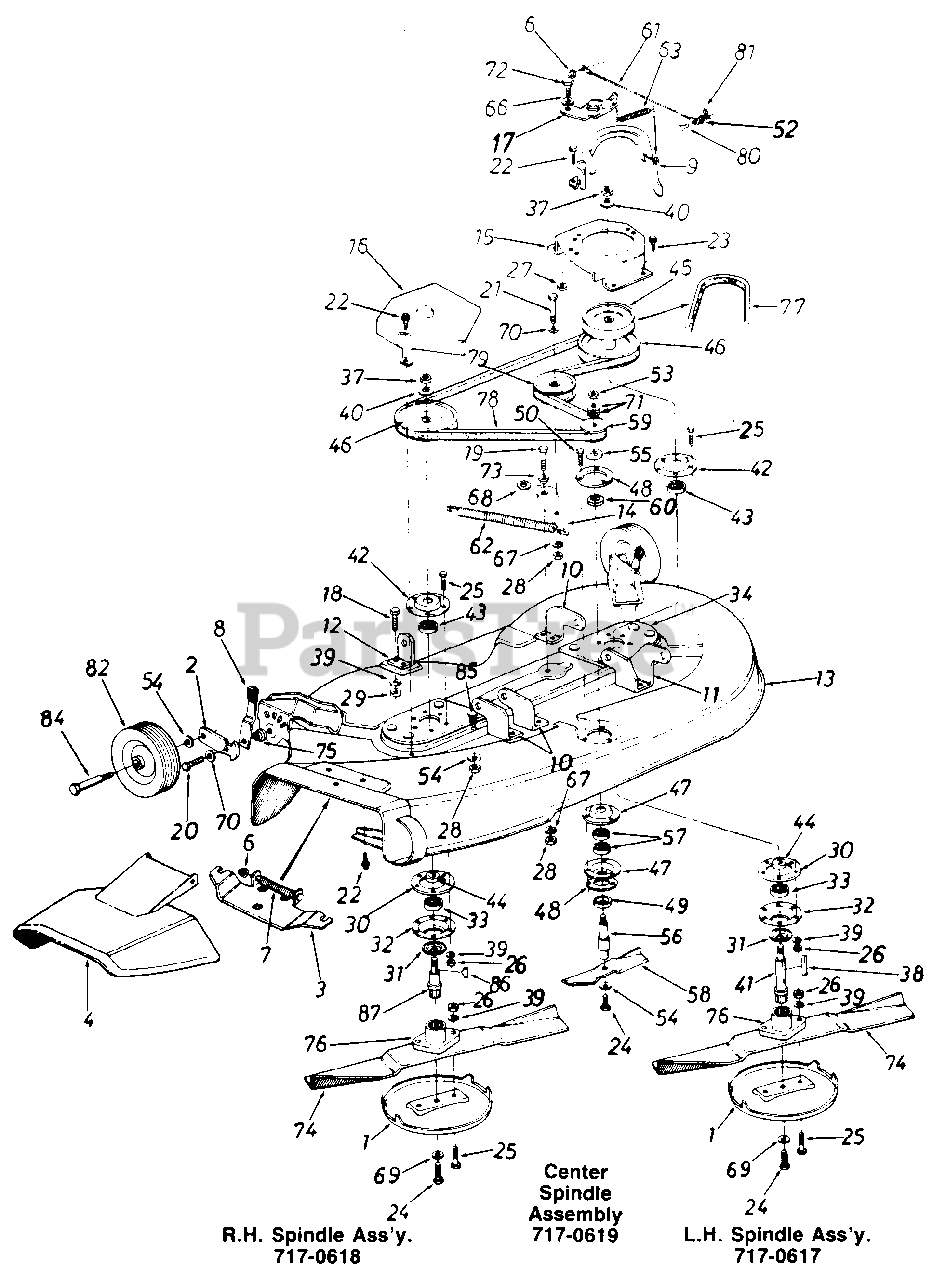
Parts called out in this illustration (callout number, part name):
1	Anti-Scalp Plate
2	Bar-Wheel Pivot
3	Adapter Plate
4	Chute Cover Ass'y.
6	Cap Speed Nut 1/4" Rod
7	Torsion Spring
8	Spring Lever Ass'y.
9	Belt Guard
12	Deck Hanger Bracket
13	44" Deck Ass'y.
14	Idler Bracket
15	Pulley Cover L.H.
18	Hex Bolt 5/16-18 x .75" Lg.
19	Hex Bolt 3/8-24 x 1.00" Lg.
20	Hex Bolt 3/8-24 x 1.25" Lg.
21	Hex Bolt 3/8-24 x 1.50" Lg.
22	Hex Wash. S-Tapp Scr. 1/4-20 x .50
23	Hex Wash. Hd. Tapp Scr. 5/16-18 x .75" Lg.
24	Hex Cent. L-Bolt 3/8-24 x .88" Lg.
25	Hex Bolt Special 5/16-24 x 1.0" Lg.
26	Hex Nut 5/16-24 Thd.
27	Hex Cent. L-Nut 5/16-18 Thd.
28	Hex Nut 3/8-24 Thd.
29	Hex Nut 5/16-18 Thd.
30	Reinforcement Plate
31	Bearing Shield
32	Open Brg. Housing 1.85 I.D.
33	Ball Brg. .787" I.D. x 1.85" O.D. x .551
34	Spindle Mounting Plate Ass'y.
37	Hex Jam Nut 5/8-18 Thd.
38	Sq. Key 3/16" x 2.25" Lg.
39	L-Wash. 5/16" I.D.
40	Bell-Wash. .630" I.D. x 1.25" O.D.
41	44" Deck Blade Spindle
42	Bearing Housing 1.85" I.D.
43	Ball Brg. .787" I.D. x 1.85" O.D. x .551
44	Spacer 1.0" O.D. x .790" I.D.
45	5/8 "V"-Pulley .79" I.D. x 5.75" O.D.
46	"V"-Pulley .79" I.D. x 6.50" O.D.
47	Bearing Housing 1-3/8" I.D.
48	Reinforcement Plate
49	Bearing Shield
50	Hex Wash. Hd. B-Tap Scr. 1/4 x.75" Lg.
52	Fl-Wash. .20" I.D. x .62" O.D.
53	Hex Jam Nut 1/2-20 Thd.
54	Bell-Wash. .400" I.D. x .88" O.D.
55	Fl-Wash. .635" I.D. x 1.04" O.D.
56	6.5" Blade Spindle
57	Ball Brg. .62" I.D. x 1.38" O.D. x .44
58	6.5" Blade
59	1/2" "V"-Puley Half .625" I.D. x 2.25" O.D.
60	Fl-Wash. 5/8" I.D. x 15/16" O.D.
61	Brake Cable 11.75" Lg.
62	Extension Spring .73" O.D. X 4.31 n Lg.
63	Ext. Spring .50" X 2.51" Lg.
66	Spring Wash. .445" I.D. x 75" O.D.
67	L-Wash. 3/8" I.D.
68	Spring Wash. .625" I.D. x .885" O.D.
69	L-Wash. 3/8" I.D.
70	Bell-Wash. .400" I.D. x 1.13" O.D.
71	Bell-Wash. 505" I.D. x 1.00" O.D.
72	Shld. Bolt .437" Dia. x .180
73	Shld. Spacer .625" I.D.
74	21" Blade
75	Shld. Spacer
76	Blade Adapter
77	"V"-Belt
78	"V"-Belt
79	Fl-Idler w/Flanges 3.50" O.D.
80	Clevis Pin 1/4 Dia. x .53" Lg.
81	Intern. Cotter Pin 5/16" Dia.
82	Deck Wheel 6.0 X 1.38
84	Shld. Bolt 3/8-16 X 1.41
85	Rib Neck Bolt
86	Sq. Key 3/16" x 3/16" X 75" Lg.
87	44" Deck Blade Spindle
